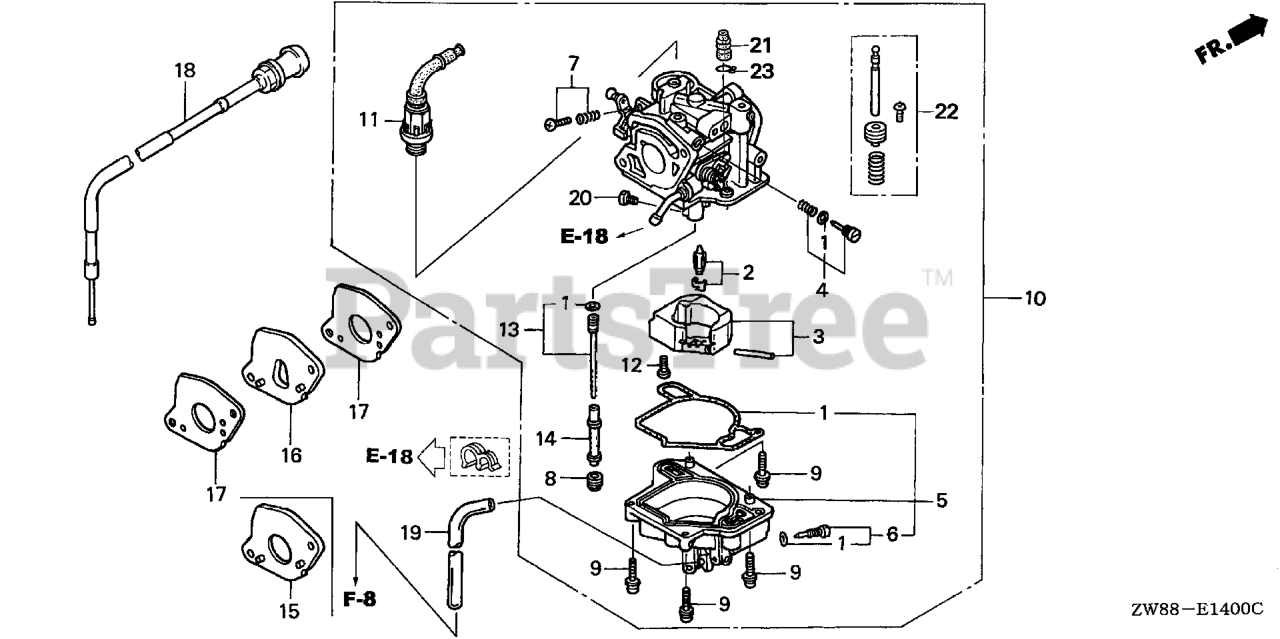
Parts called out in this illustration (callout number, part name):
1	GASKET SET
2	VALVE SET, FLOAT
5	CHAMBER SET, FLOAT
6	SCREW SET, DRAIN (CARBURETOR NO.)
7	SCREW SET
8	SCREW, PLUG
9	SCREW-WASHER
10	CARBURETOR ASSY. (BJ02A D)
11	VALVE SET, STARTER
12	SCREW, PAN
13	JET SET (#45)
14	NOZZLE, MAIN
16	INSULATOR, CARBURETOR
17	GASKET, CARBURETOR
18	CABLE, CHOKE
19	BULK HOSE, VINYL (4X7X8000) (95003-07(95003-07001-60M) (CARBURETOR NO.)
20	JET, MAIN (#100)
20	JET, MAIN (#102)
20	JET, MAIN (#105)
22	PLUNGER SET, ACCELERATOR PUMP
23	CLIP, TUBE
